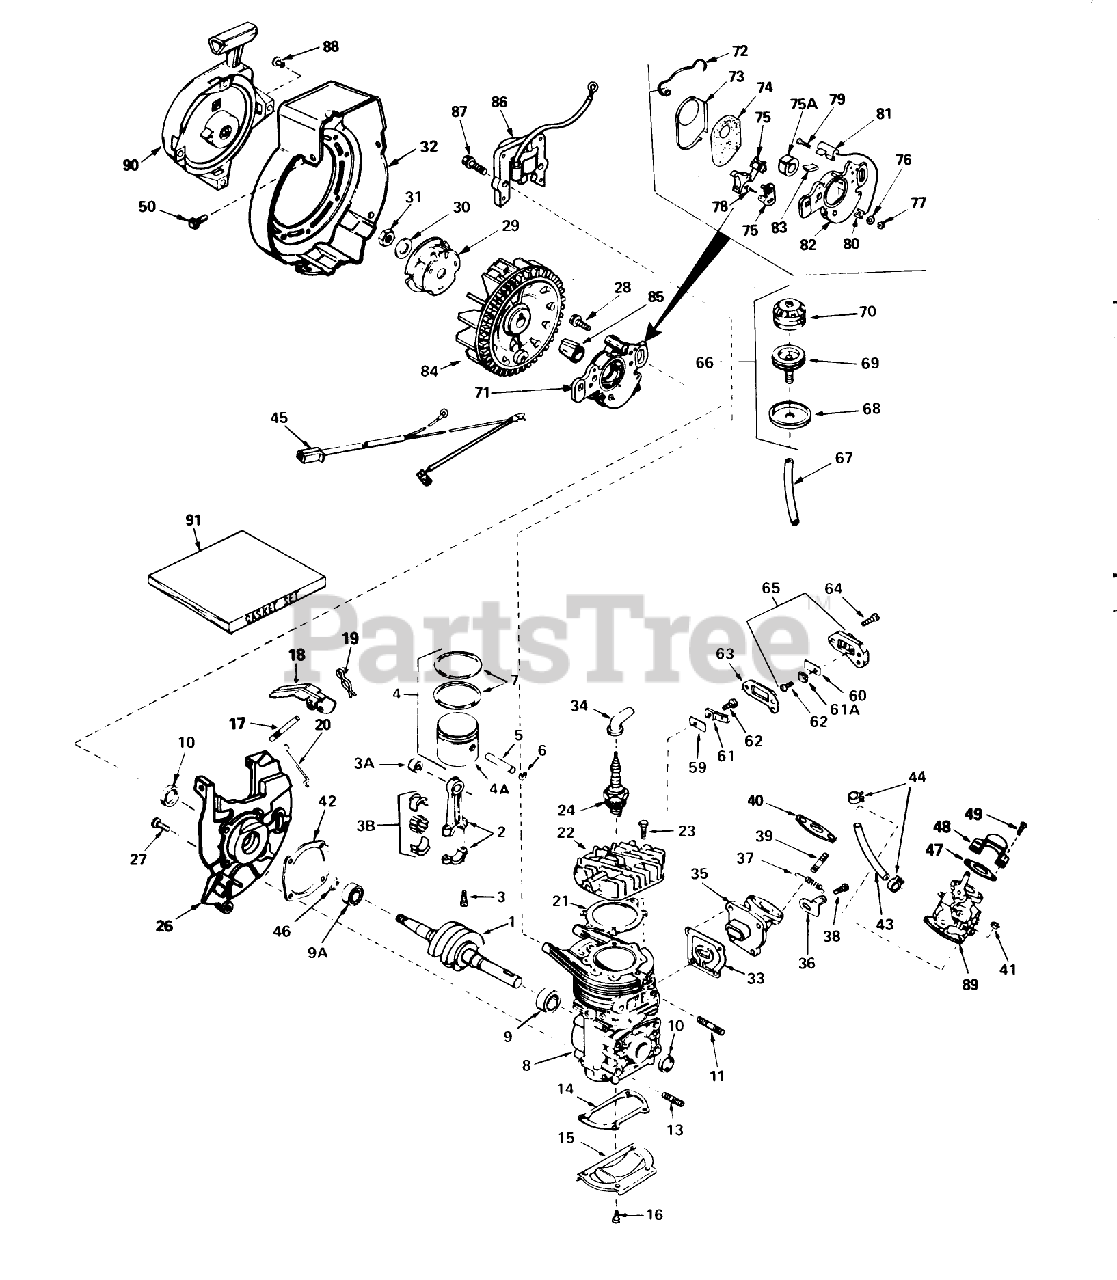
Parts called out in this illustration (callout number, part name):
1	Crankshaft
2	Rod Assembly, Connecting (Incl. #3, 3A 3B)
3	Bolt-Rod, Connecting
3A	Bearing-Cartridge
4	Piston, Pin Ring Assy. (Incl. Ref. #6 thru 9)
4A	Piston
5	Pin, Piston
6	Ring-Retaning
7	Ring Set
9	Bearing-Cartridge
9A	Bearing-Ball
10	Seal-Oil
14	Gasket, Cover
15	Plate, Cover
16	Screw (T-25, 10-24 x 1/2)
17	Shaft, Air Vane
18	Vane Assy., Air
19	Clip,Air Vane
20	Link-Governor
21	Gasket, Head
22	Head-Cylinder
23	Screw (T-30, 1/4-20 x 3/4)
24	Head Adjustment Knob
26	Base Assy., Blower Housing (Incl. Ref. #10 17)
27	Screw
28	Screw, Hex Washer Hd.
29	Cup-Starter
30	Washer-Spring
31	Nut-Flywheel
32	Housing-Blower
33	Gasket, Port
34	Cover-Spark Plug
35	Elbow Assy., Adapter
36	Lever, Adjusting
37	Spring, Adjusting Lever
38	Screw
39	Stud Carburetor
40	Gasket, Carburetor
41	Locknut
42	Gasket, Shroud Base
43	Line-Fuel
44	Clamp-Line, Fuel
45	Harness, Wire
46	Ring, Retaining
47	Gasket
48	Baffle-Carburetor
49	Screw
50	Screw-Hex, Hd.
59	Reed, Compression Release
60	Reed, Compression Release
61	Plate, Reed Hold Down
61A	Plate, Reed Hold Down
62	Screw
63	Gasket, Compression Release
64	Screw
65	Cover Assy., Compression release (Incl. Nos. 60, 61A 62)
66	Primer Assy.
67	Line, Primer
68	Retainer, Primer Bulb
69	Body, Primer
70	Bulb-Primer
71	Stator Plate Assy. (incl. Nos. 107, 111 thru 118 120)
72	Spring Breaker Box
73	Cover-Dust
74	Gasket Dust
75	Breaker Assy.
75A	Cam, Breaker
76	Washer
77	DECAL
78	Breaker Screw
79	Condenser Screw
80	Terminal, Ground
81	Condenser
82	Stator Plate
83	Felt,Cam Wiper
84	FIywheel
85	SHIELD
86	Lamination Coil Assy. (Incl. No. 42)
87	Screw
88	Rivet, Pop (3/16" dia.)(Can be purchased locally)
89	Carburetor (Incl. Ref. #40)
90	Starter-Rewind
91	Gasket Set (Incl. items marked *)
